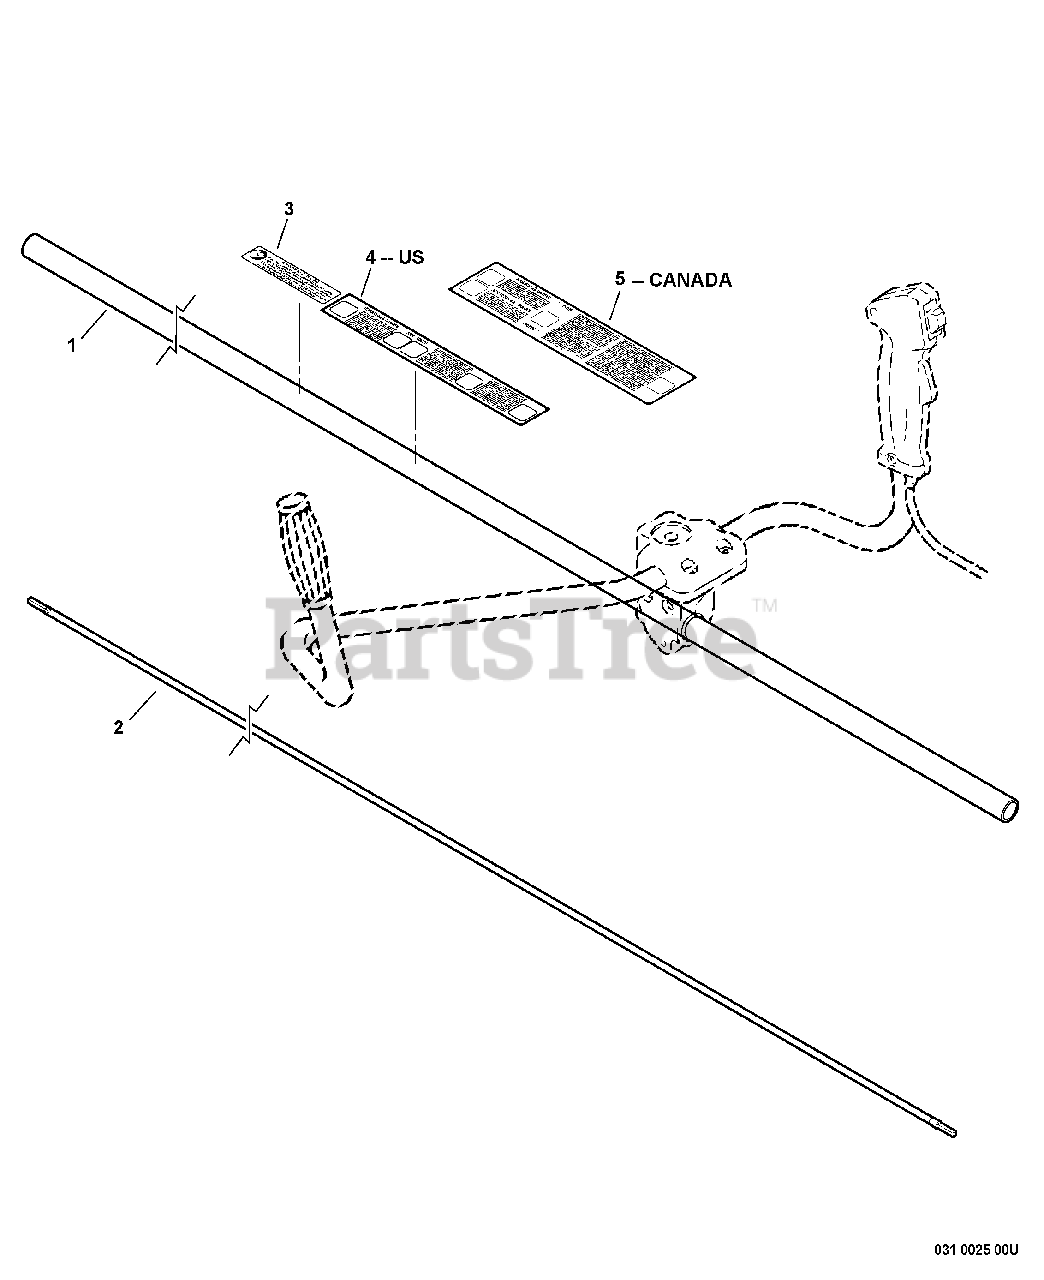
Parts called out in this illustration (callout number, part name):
1	PIPE, MAIN
2	DRIVESHAFT
3	LABEL, CAUTION
4	LABEL, CAUTION
5	LABEL, CAUTION
